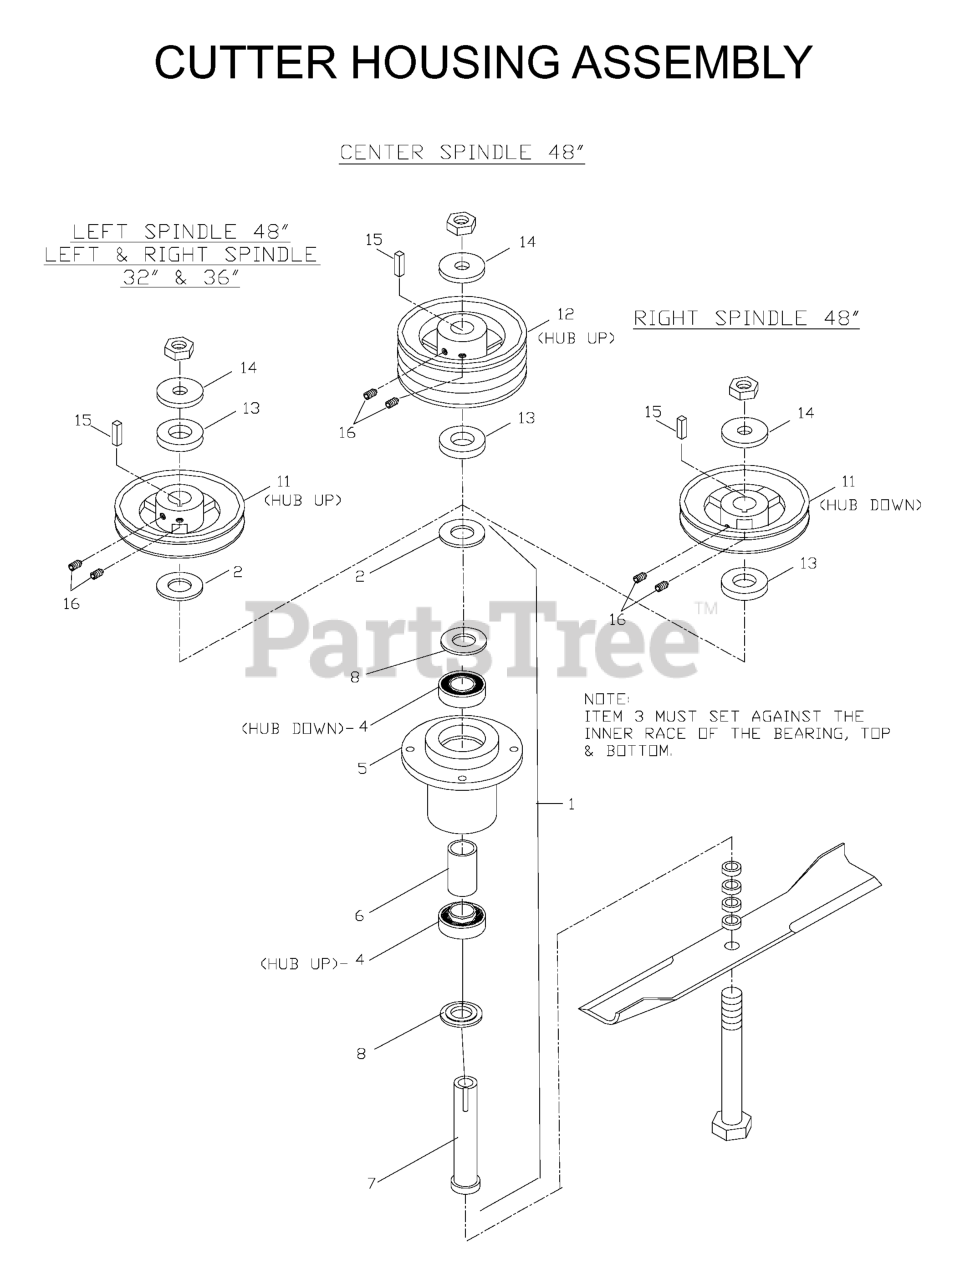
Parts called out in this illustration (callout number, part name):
1	HOUSING ASSEMBLY
2	MACHINERY BUSHING 10 GA.
3	BUSHING.MACHINE.18.GAUGE
4	BEARING
7	SPINDLE SHAFT
8	PULLEY W/SETSCREWS
9	PULLEY, DOUBLE W/SETS
11	WASHER, SUPPORT
12	KEY 1/4 SQ X 1 1/8
13	SET SCREW 5/16 NYLOC
